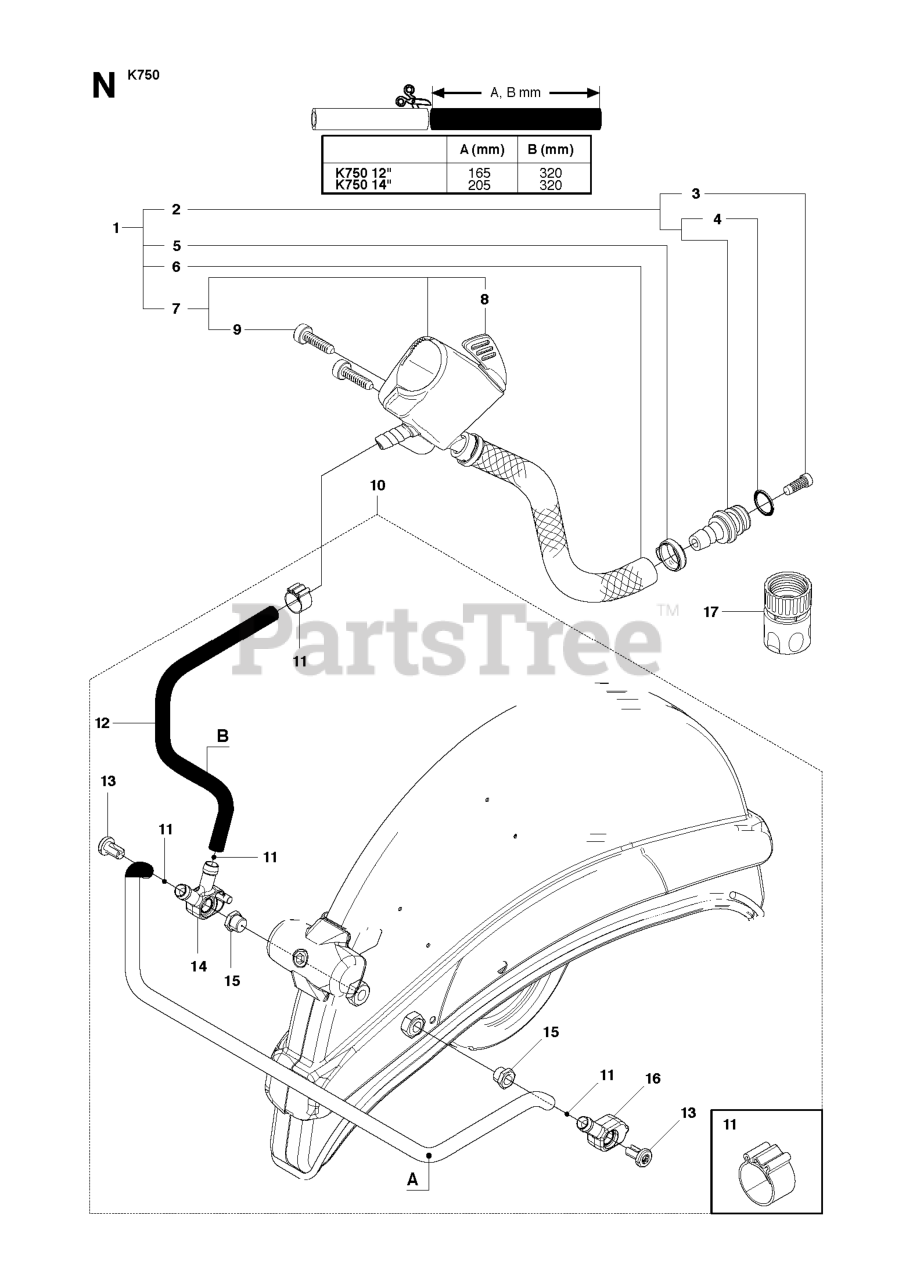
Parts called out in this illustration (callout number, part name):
1	HOSE KIT, WET CUT KIT, HANDLE
5	HOSE CLAMP
7	VALVE ASSY
11	HOSE CLAMP
12	HOSE L620
17	COUPLER, 1/2" HOSE W/STOP ORIG
17	FEMALE QUICK COUPLER
